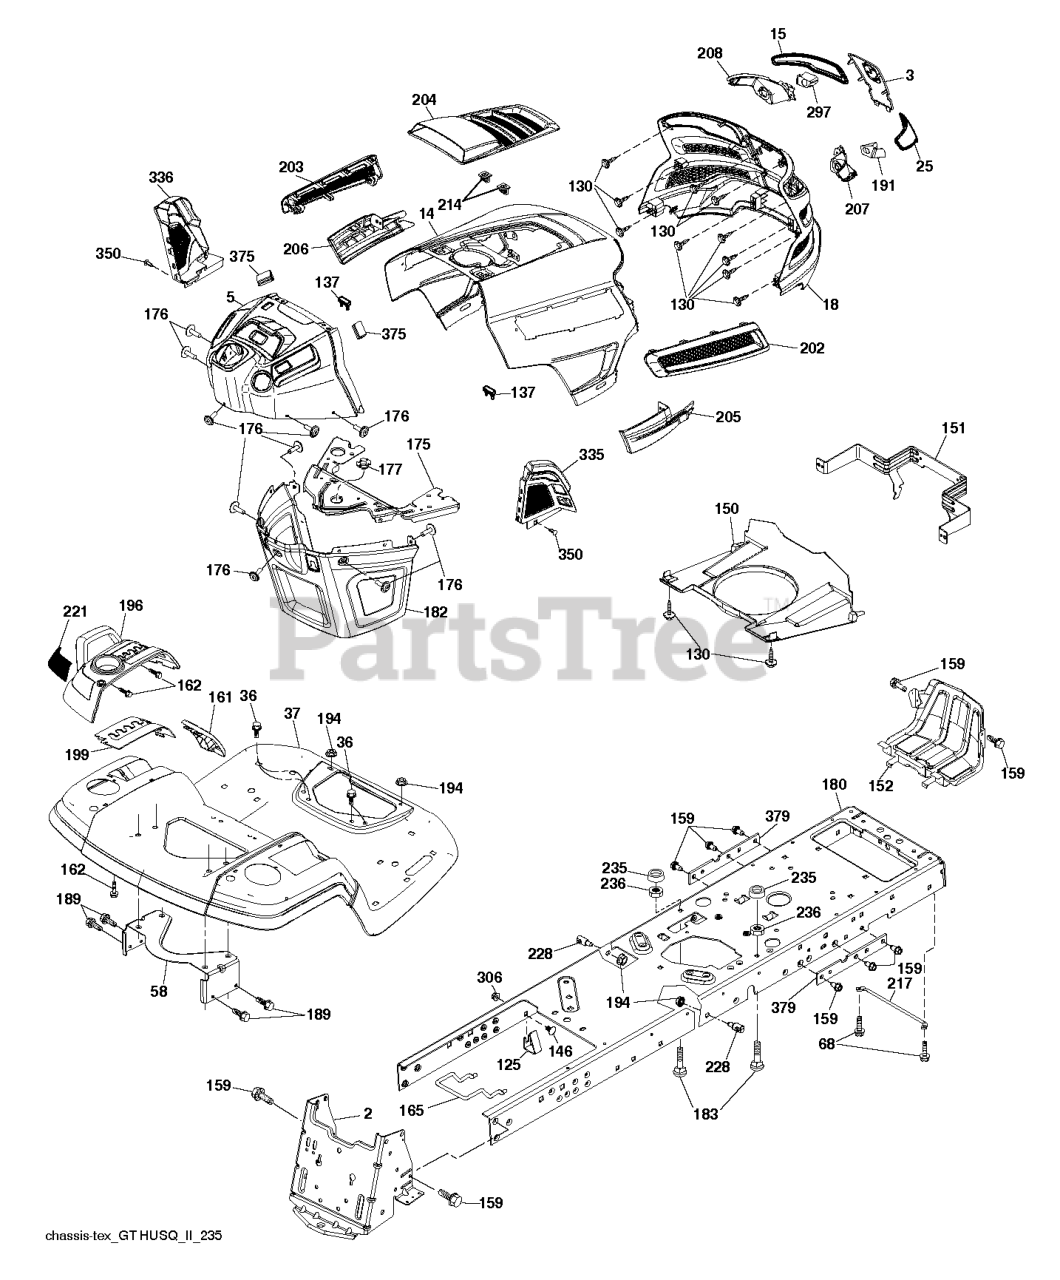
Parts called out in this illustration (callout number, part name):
2	DRAWBAR.STGT
3	APPLIQUE.SUBASM.GT.HUSQ.II
5	DASH.UPR.GT2.SRV.MIND.PTO
14	HOOD.ASM.HUSQVARNA.GT.TEX.ORAN
15	LENS.HEADLIGHT.LH.GTII.2011
18	GRILLE SUBASM.GT.II.LOW.HDLGHT
25	LENS.HEADLIGHT.RH.GTII.2011
36	SCREW 5/16"
37	FENDER.PNT.TX.GT.CH/FW/DL.HUSQ
58	BRKT.SUPPORT.FNDR/TANK
68	SCR 5/16-18 X 1/2 SELFTAP ZN
125	CLIP.FUEL.LINE
130	SCREW.#10 X 0.750.BOS
137	BUMPER DASH
146	BOLT.RDHD.SHT.SQNK.3/8-16X5/8
150	AIR.DUCT.GTV.BLACK
151	BRACKET.PIVOT.HOOD.GT.HUSQ.II
152	SHIELD.BROWNING.PNT.GT.V2
159	SCREW, 3/8-16X3/4
161	CONSOLE.WINDOW.FUEL.HUSQ.GT
162	SCREW.HI-LO.CONSOLE
165	SUPPORT.TANK.REAR.B/TE
175	PLATE.PNT.CROSSMEMBER.HUSQ/PRE
176	SCREW.#10-24X5/8.RN.QU
177	BUSHING STEERING
180	CHASSIS.LT/GT.BOLTED
182	DASH LOWER.HUSQ.PRED NO CRUISE
183	BOLT.5/16-18X1-1/4 FULL THD
189	SCREW
191	INSERT.REFLECTIVE.RH.HUSQ.GTII
194	NUT LOCK HEX FLANGE 5/16-18
196	SUBASM.CONSOLE.HUSQ.GT.DECKLFT
199	PLATE.DECK.LIFT.HUSQVARNA.GT
202	VENT.SIDE.RH.GT.HUSQ.II.
203	VENT.SIDE.LH.GT.HUSQ.II.498
204	VENT.TOP.HUSQ.GT2
205	SIDE.TRIM.RH.GT.HUSQ.II
206	SIDE.TRIM.LH.GT.HUSQ.II.GRAY
207	HEADLIGHT.CUP.BEZEL.HUS.GT2.RH
208	HEADLIGHT.CUP.BEZEL.HUS.GT2.LH
214	CLIP.RETAINER.TINNER.
217	ROD.PIVOT.HOOD
221	REFLECTOR.LH.TEX GT HU
228	STUD.FASTNER.W/ANTI-ROTATE
235	SPACER FENDER
236	NUT.CENTERLOCK.5/16-
297	INSERT.REFLECTIVE.LH.HUSQ.GTII
306	NUT LOCK FLG 3/8-16 UNC
335	COVER.LOWER.DASH.RH.BLACK
336	COVER-LH.LOWER.DASH.GT2.BLACK
350	CLIP.X-MAS.TREE
375	BUMPER CLIP-ON. DASH 1"
379	CHASSIS.PLATE.REINFORCEMNT.431
